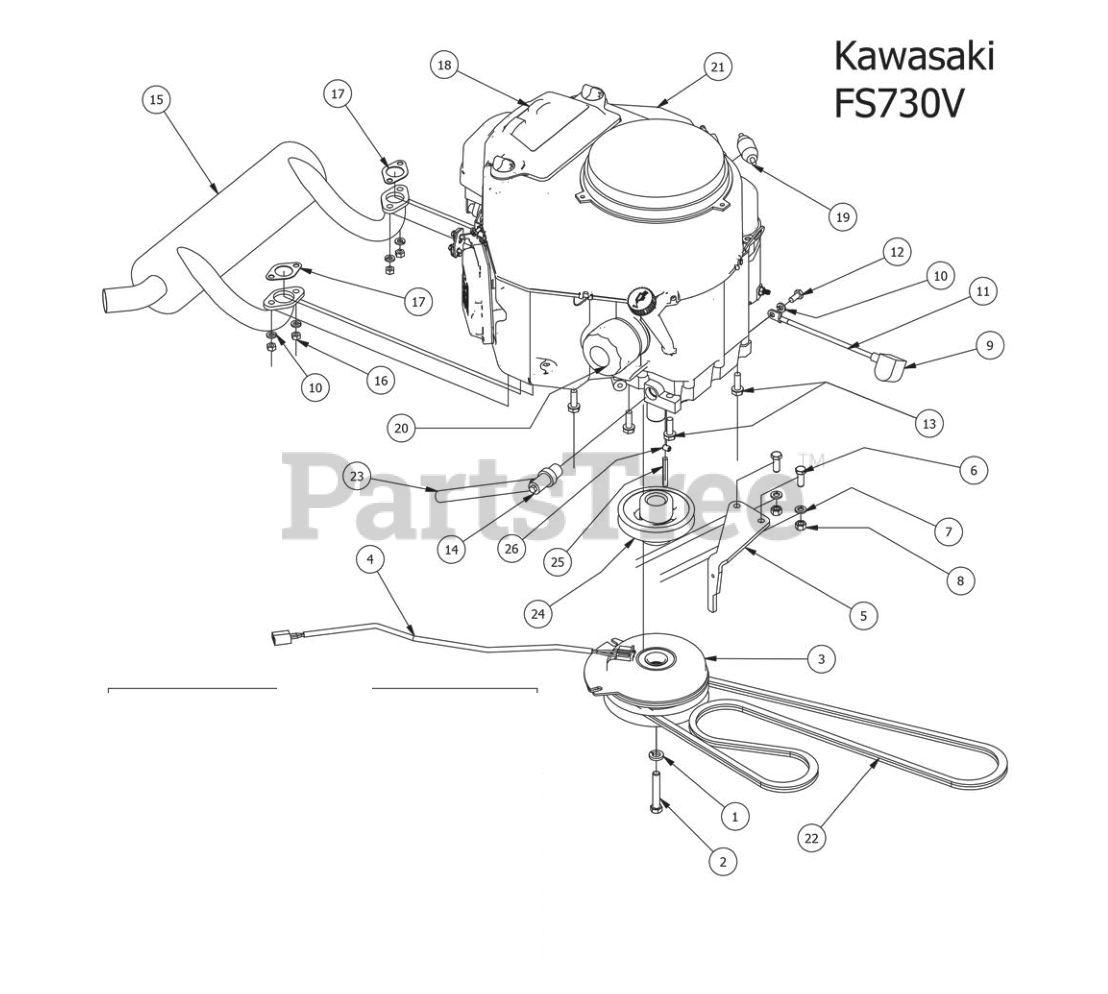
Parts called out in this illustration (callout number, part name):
1	7/16" Lock Washer
2	7/16" x 2 1/2" Hex Bolt
3	Clutch Assembly
4	Clutch Pigtail
5	PTO Engager Holder
6	3/8" x 1" Hex Bolt
7	3/8" Lock Washer
8	3/8" Hex Nut
9	Black Boot For ground cable
10	5/16" Lock Washer
11	Starter to chassis cable
12	M8x1.20x20MM Hex head bolt
13	3/8 x 1 1/8 bolt
15	Exhaust Kawasaki FS730V Outlaw 2013
16	M8-1.25 Zinc Nut
17	Exhaust gasket
18	Kaw air Filter For Engine
19	Universal inline Fuel Filter
20	Oil Filter
21	FS730V Engine
23	1/2 Clear Braded Hose Priced/Foot
24	4 3/4 Motor Pulley
25	1/4 x 2 Square key Stock
26	5/16 Set Screw
